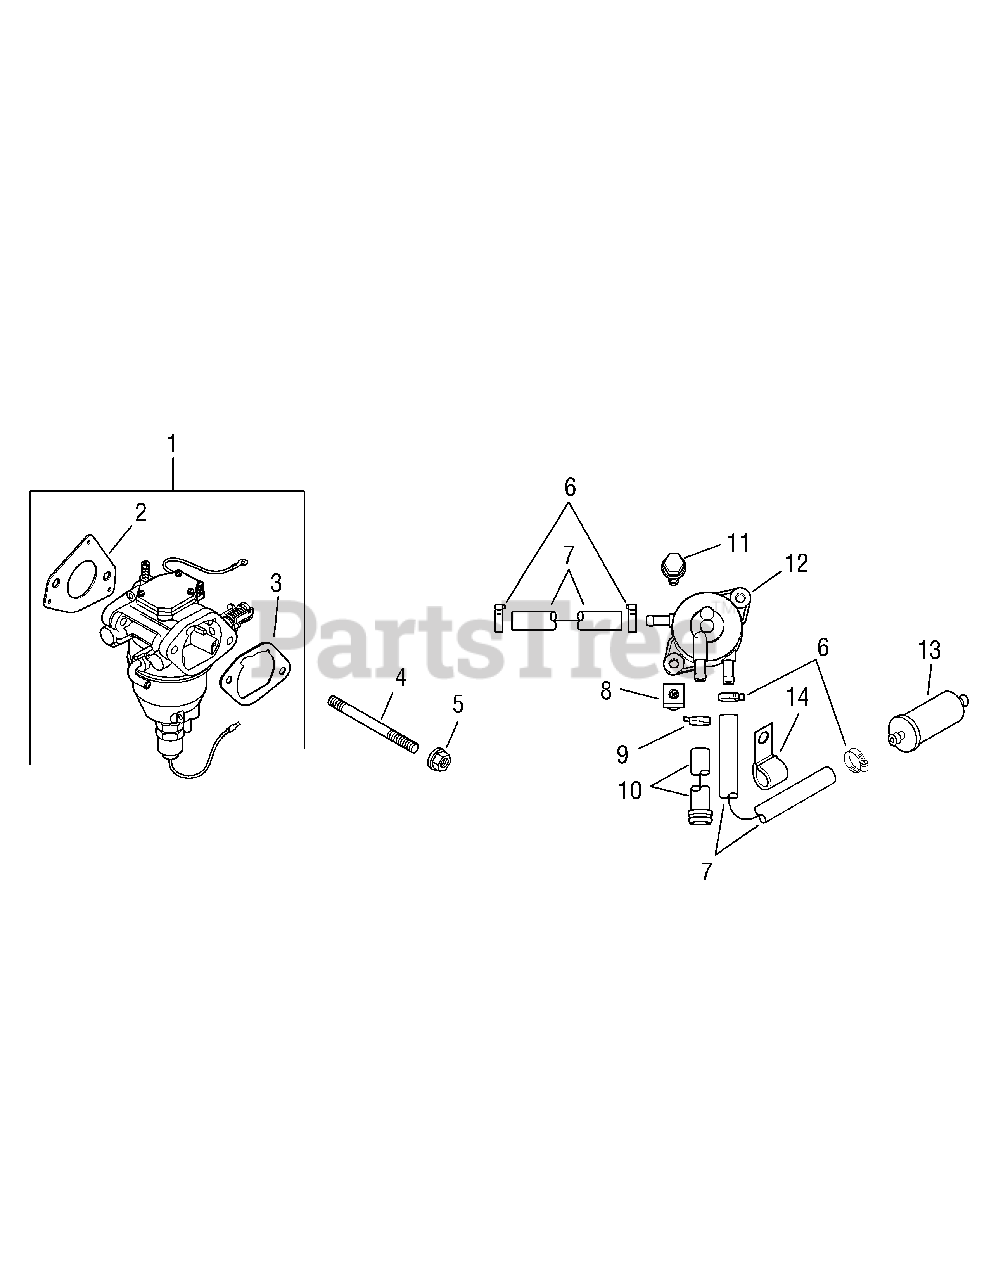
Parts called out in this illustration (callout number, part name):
1	Kit, carburetor w/gaskets (Includes 2,3)
2	Gasket, carburetor
3	Gasket, air cleaner base
4	Stud, carburetor
5	Nut, hex. flange M6x1.0
6	Clamp, hose
7	Line, fuel (Fuel line comes in lengths of 24")
8	Nut, plastic
10	Hose, fuel pump
11	Screw, hex. cap M6x1.7x18
12	Pump, pulse fuel
13	Filter, fuel
